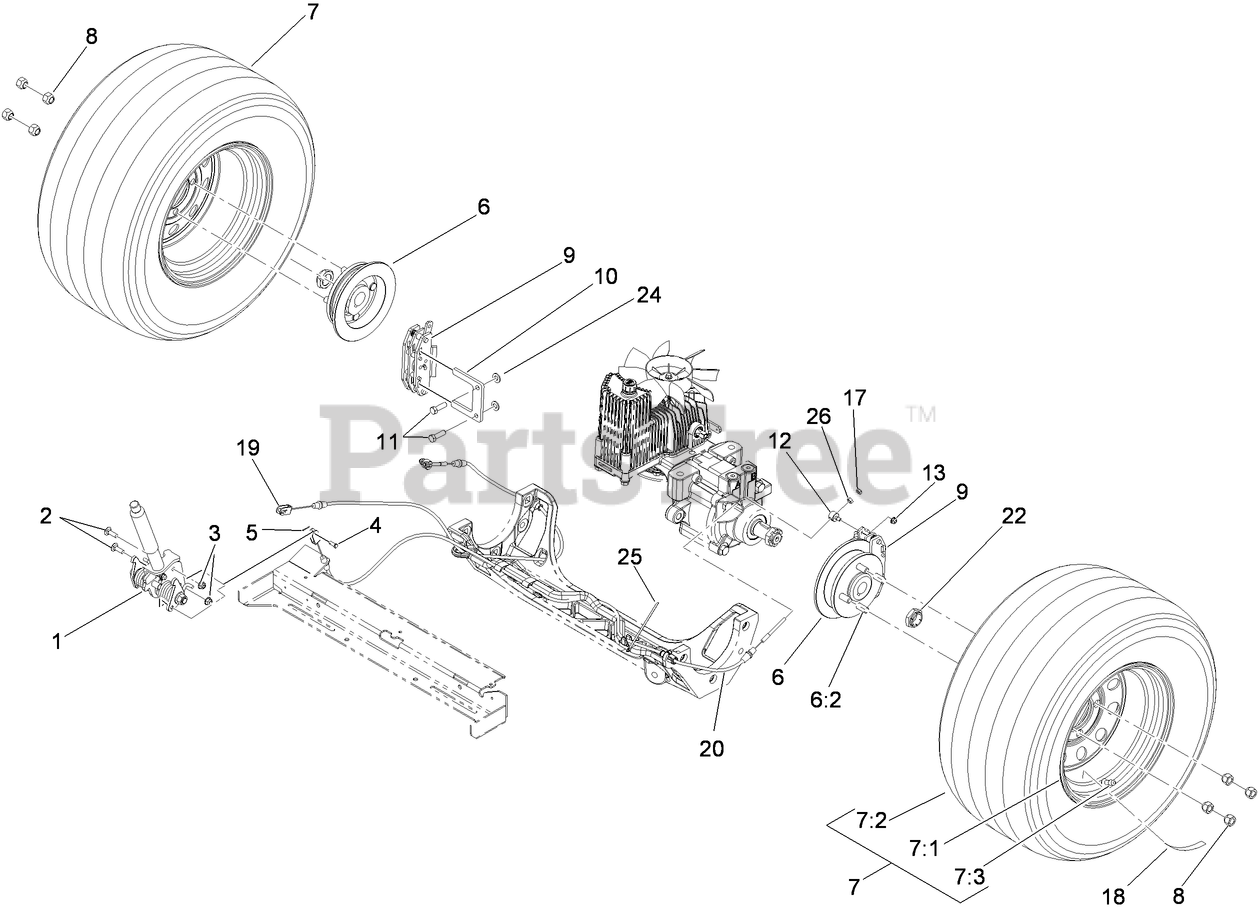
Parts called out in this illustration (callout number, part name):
1	BRAKE HANDLE ASM
2	BOLT-CARR
3	NUT-HF, NI
4	PIN-CLEVIS
5	PIN-COTTER
6	WHEEL HUB ASM
6:2	STUD-WHEEL
7	WHEEL AND TIRE ASM
7:3	STEM-VALVE
8	NUT-LUG
9	CALIPER-BRAKE
10	PLATE-MOUNT, BRAKE
11	SCREW-LOCK, PATCH
12	SWIVEL
13	NUT-HF
17	NUT-LOCK, NI
18	DECAL-WHEEL NUT TORQUE
22	LOCKNUT
24	WASHER-FLAT
25	TIE-CABLE
26	NUT-HEX
